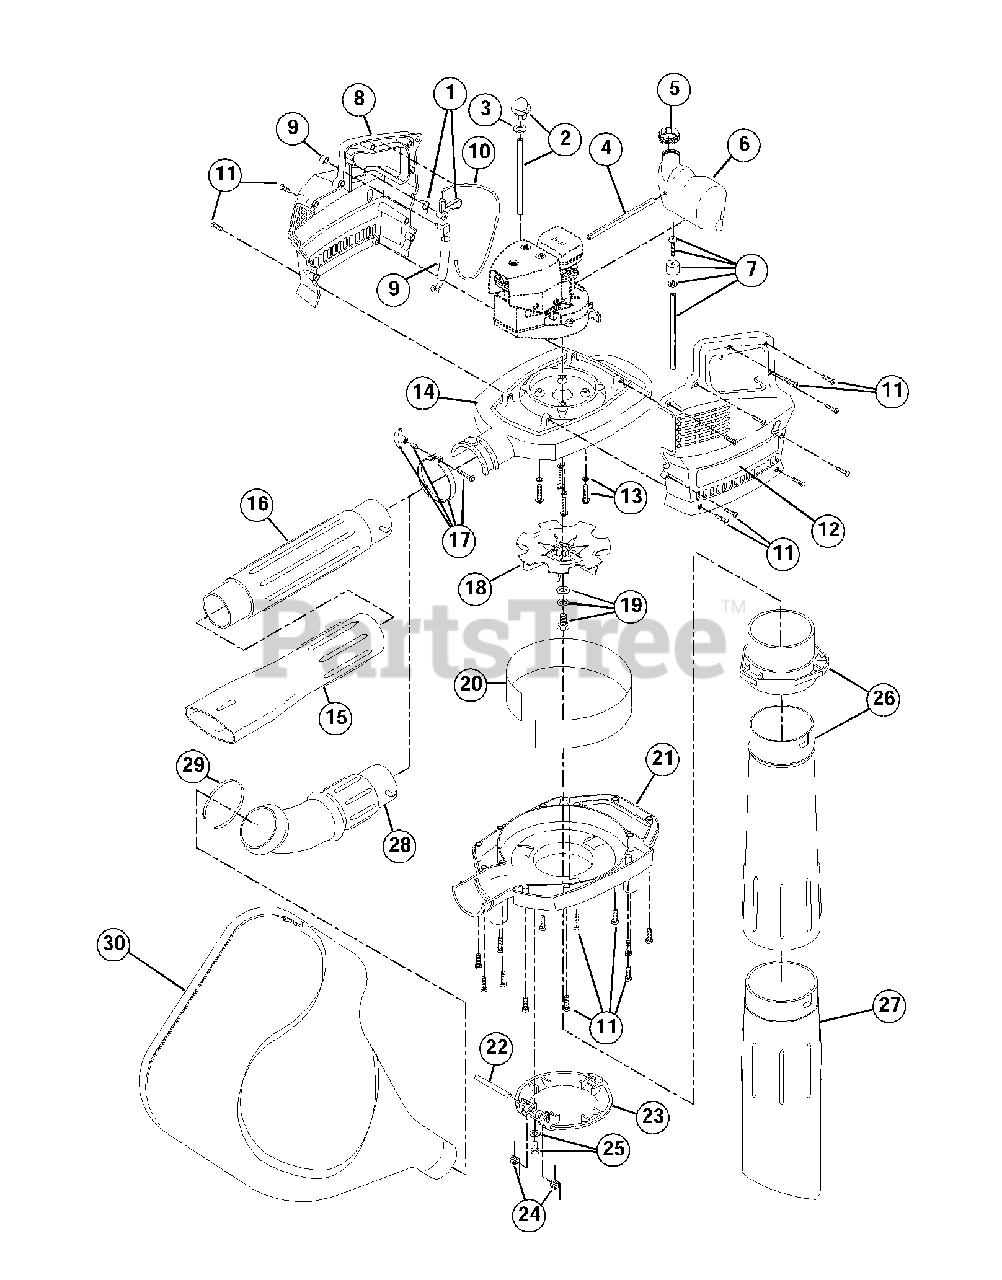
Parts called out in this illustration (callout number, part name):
1	Trigger Assembly
2	Primer Bulb and Hose Assembly
3	Primer Washer
4	Return Line
5	Fuel Cap Assembly
6	Complete Fuel Tank Assembly
7	Fuel Line Assembly
8	R.H. Engine Cover
9	Switch and Lead Assembly
10	Throttle Wire
12	L.H. Engine Cover
13	Mounting Screw Assembly
14	Upper Blower Housing
15	Blower Tube W/Nozzle
16	Blower Tube
17	Clamp Assembly
18	Impeller
19	Mounting Bolt Assembly
20	Impact Shield
21	Lower Blower Housing
22	Hinge Shaft
23	Intake Cover
24	Spring Set
25	Mounting Screw Assembly
26	Upper Vacuum Tube and Adapter
27	Lower Vacuum Tube
28	Elbow
29	Clamp
30	Vacuum Bag Assembly
